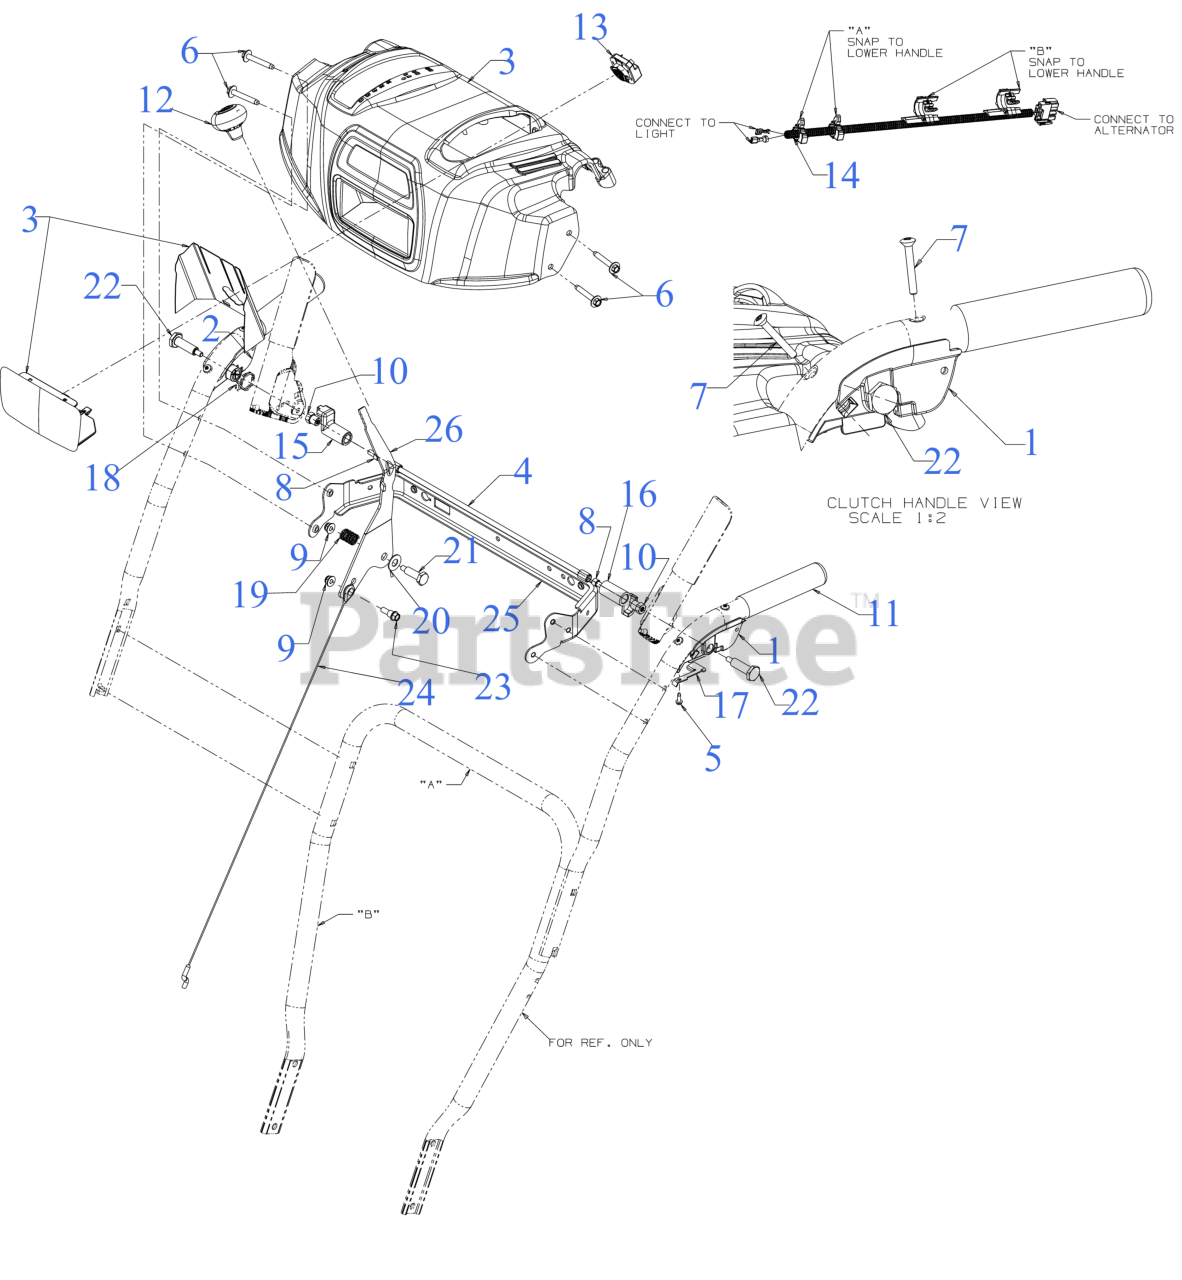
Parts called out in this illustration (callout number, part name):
1	CLUTCH LOCK HANDLE ASSEMBLY (LH)
2	CLUTCH LOCK HANDLE ASSEMBLY (RH)
3	HANDLE PANEL ASSEMBLY
4	PIVOT ROD
5	SCREW #8-16 x .50
6	SCREW 1/4-20 x 1.625
7	SCREW #10-24 x 1.375
8	SCREW 1/4-20 x .50
9	FLANGE LOCK NUT
10	HEX NUT W/PATCH
12	SHIFT KNOB
13	LED HEADLIGHT & SOCKET (150 LUMNES)
14	LIGHT HARNESS
15	LOCK PLATE
16	CLUTCH LOCK CAM
17	CLUTCH SPRING
18	TORSION SPRING
19	COMPRESSION SPRING
20	FLAT WASHER .38X.88
20	FLAT WASHER .401X.88
21	SHOULDER SCREW
22	SHOULDER SCREW .437 x 1.345 1/4-20
23	SHOULDER SCREW .342X.335X1/4-20
24	SELECTION CABLE
24	SPEED SELECTOR CABLE (PLASTIC)
29	SHIFT LEVER
